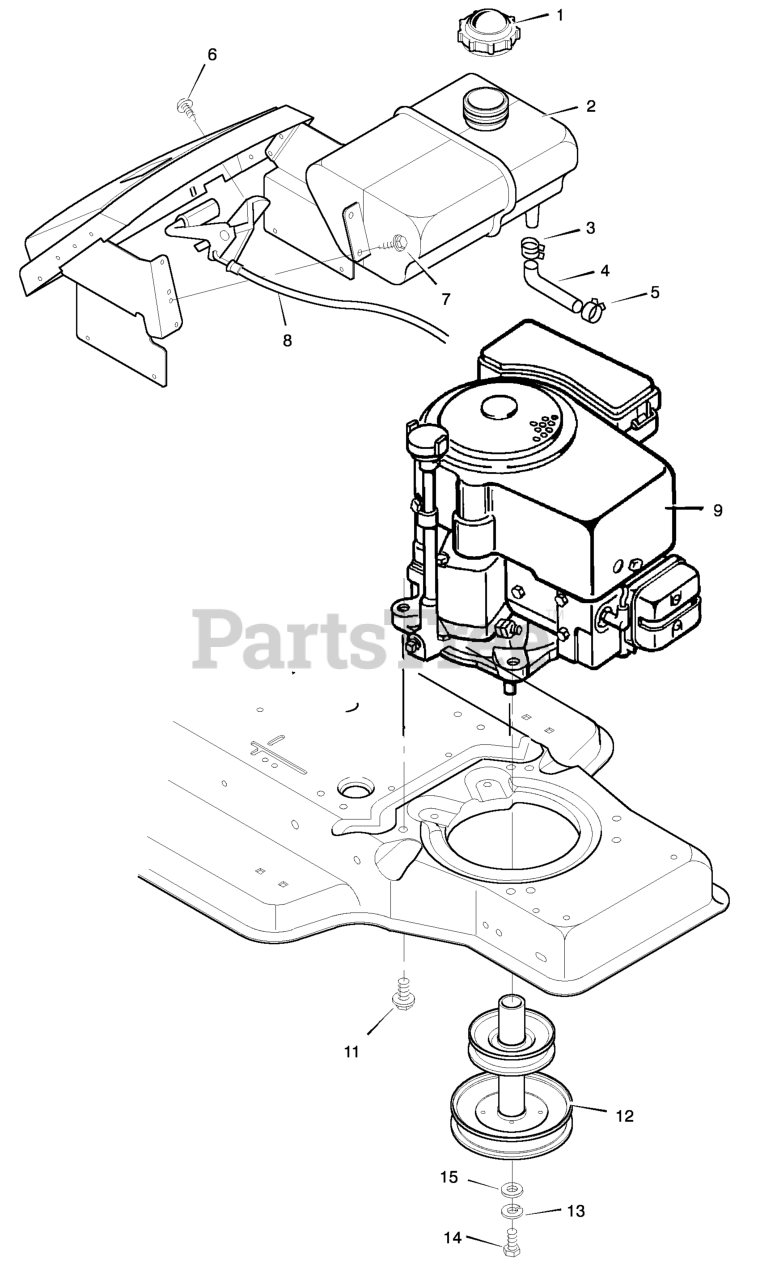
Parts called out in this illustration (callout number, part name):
1	Fuel Cap
2	Fuel Tank
3	Hose Clamp
4	Fuel Line
5	Hose Clamp
8	Throttle Control
9	Engine *
11	Bolt, Engine Mount
12	Stack Pulley Assembly
13	Lockwasher
14	Bolt, Hex
